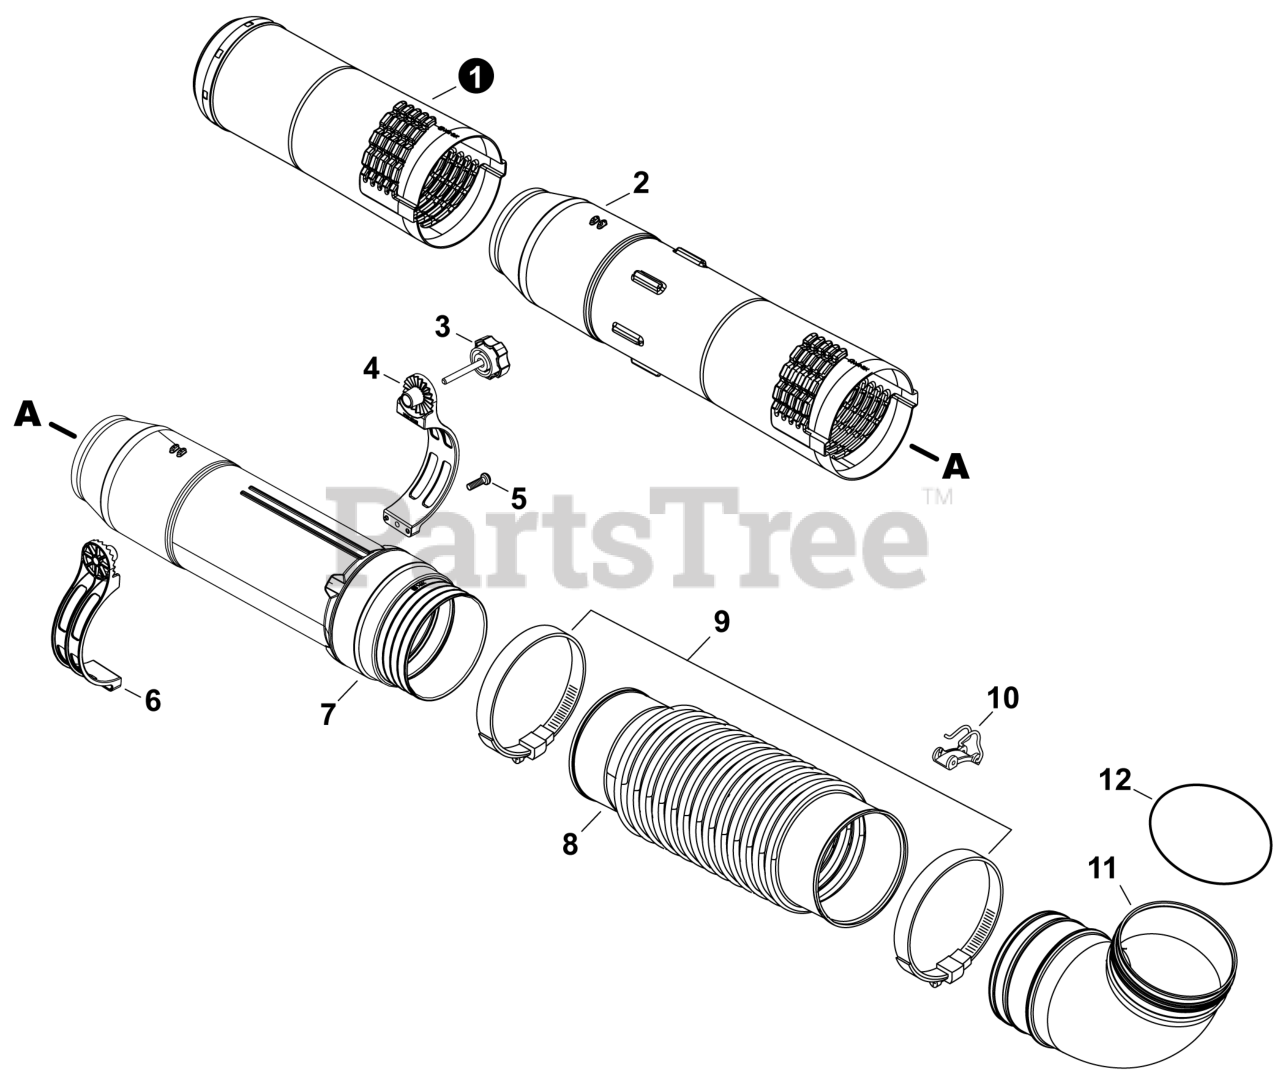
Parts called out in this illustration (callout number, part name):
1	TUBE, BLOWER - NOZZLE
2	TUBE, BLOWER - STRAIGHT
3	KNOB, SCREW
4	BRACKET, HANDLE - RIGHT
5	BOLT, TORX 5x20
6	BRACKET, HANDLE - LEFT
7	TUBE, BLOWER - SWIVEL
8	TUBE, BLOWER - FLEXIBLE
9	CLAMP - BAND
10	CLIP, CABLE
11	TUBE, BLOWER - ELBOW
